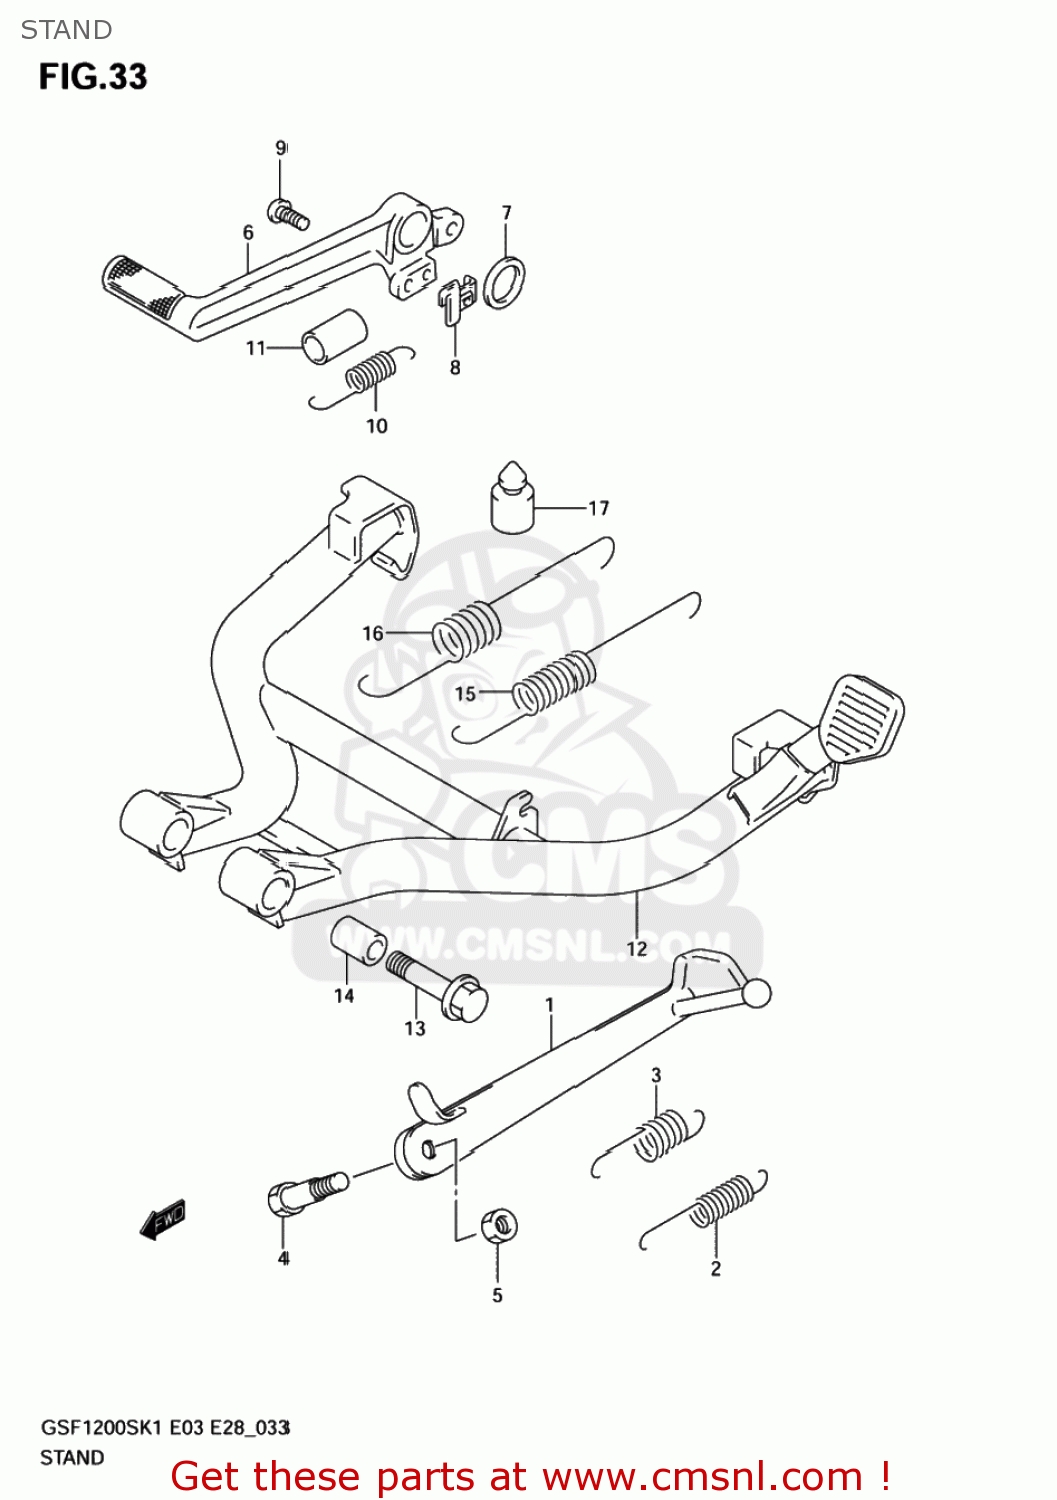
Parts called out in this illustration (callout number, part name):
1	STAND,COMP,PRO
2	SPRING
3	SPRING
4	BOLT(10X37.5)
5	NUT,PROP STAND
6	PEDAL,BRAKE
7	WASHER(18X24X1)
8	BRACKET,STOP LAMP SWITCH SPR
9	SCREW
10	SPRING
11	TUBE,BRAKE SPRING GUIDE
12	STAND,CTR
13	BOLT(10X48)
14	SPACER(10X16X25.5)
15	SPRING
16	SPRING OUTER
17	CUSHION
